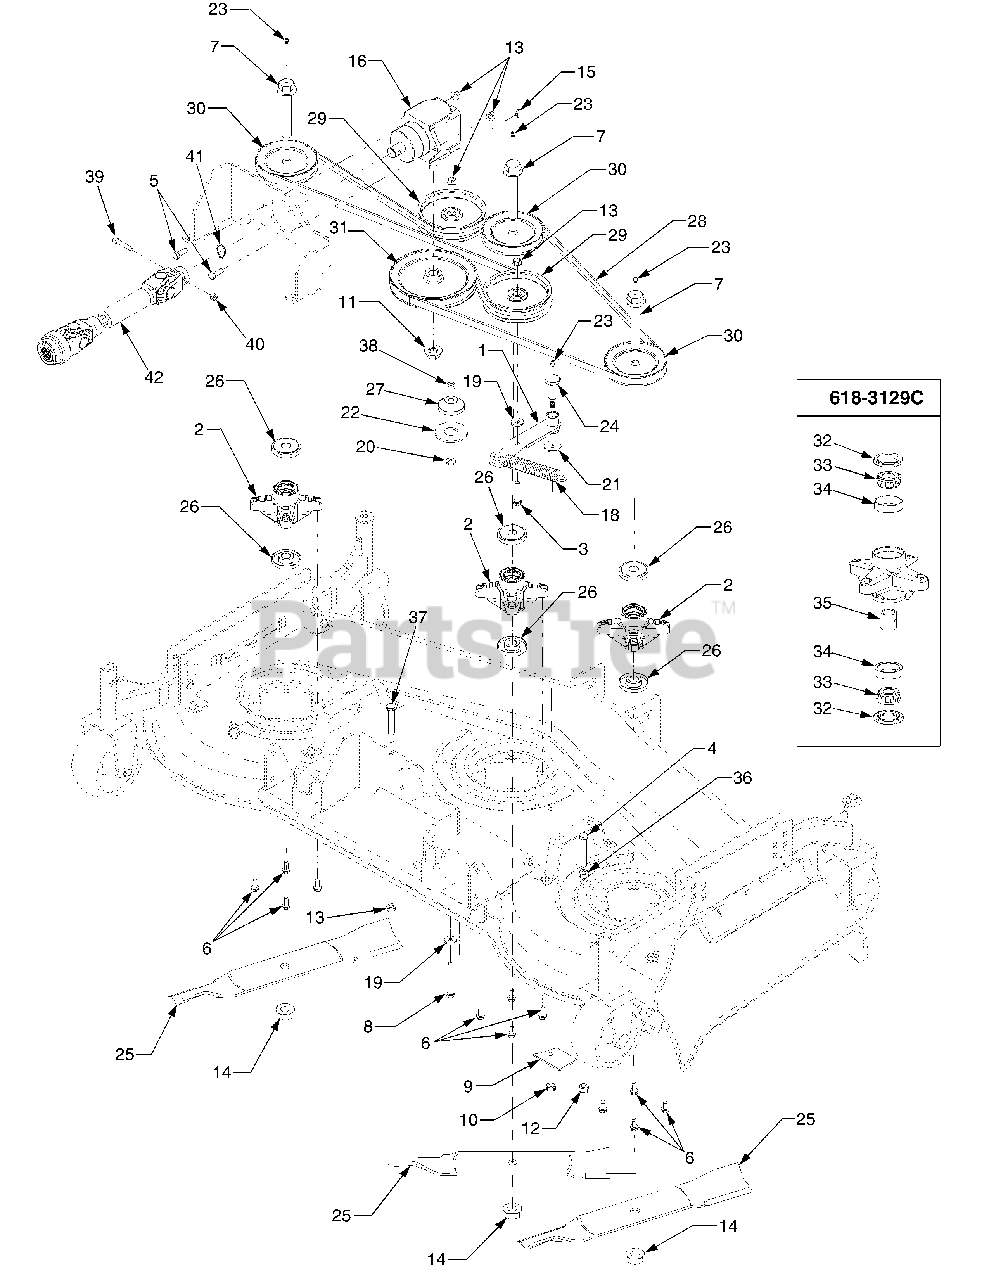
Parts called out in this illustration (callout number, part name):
1	Bracket, Idler
2	Assembly, Spindle (Includes Ref. Nos. 32 thru 35)
3	Screw, Hex Cap 3/8-16 x 1.75 GR5
4	Screw, Hex Cap 5/16-18 x 2.25 GR5
5	Screw, Hex Cap 3/8-16 x 1.25 GR5
6	Screw, Hex Wash Hd Tapp 5/16-18 x .75
7	Bolt, Spindle, 3/4-16 x 4.25
8	Screw, Hex Cap 3/8-16 x 3.0 GR8
11	Nut , Hex Flanged 5/8-18
12	Nut, Hex Nylon Lock 5/16 -18
13	Nut, Flange Lock 3/8-16
14	Nut, Hex Flange, 3/4-16
15	Key, Hi-Pro
16	Drive, Right Angle
18	Spring, Extension 6.14" Lg.
19	Washer, Flat .385 x 1.0 x .135
20	Washer, Flat, .39 x .75 x . 105
21	Washer, Flat, .45 x 1.25 x .164
22	Washer, Flat 1.063 x 2.5 x .16
23	Fitting, Lube
24	Bolt, Shoulder .68" Dia. x 1.59
25	Blade, High Lift 20.5" Lg.
26	Spacer, Deck Spindle
27	Spacer, Idler
28	Belt, “V" 133" Lg.
29	Pulley, Flat Idler
30	Pulley, “V"
31	Pulley, Drive
32	Seal, Oil
33	Bearing, Cone
34	Cup, Bearing
35	Spacer, Bearing
36	Nut, Hex Jam, 5/16-18 Lock
37	Screw, Shoulder, 1/2 x 2.5
38	Spacer, .38 ID x .625 OD x .21
39	Screw, Socket Hd. 5/16-18 x 1.75 GR5
40	Nut, Hx Insert Lck, 5/16-18 Gr5
41	Ring, Retaining, (.875 Shaft)
42	Shaft, Deck Drive
